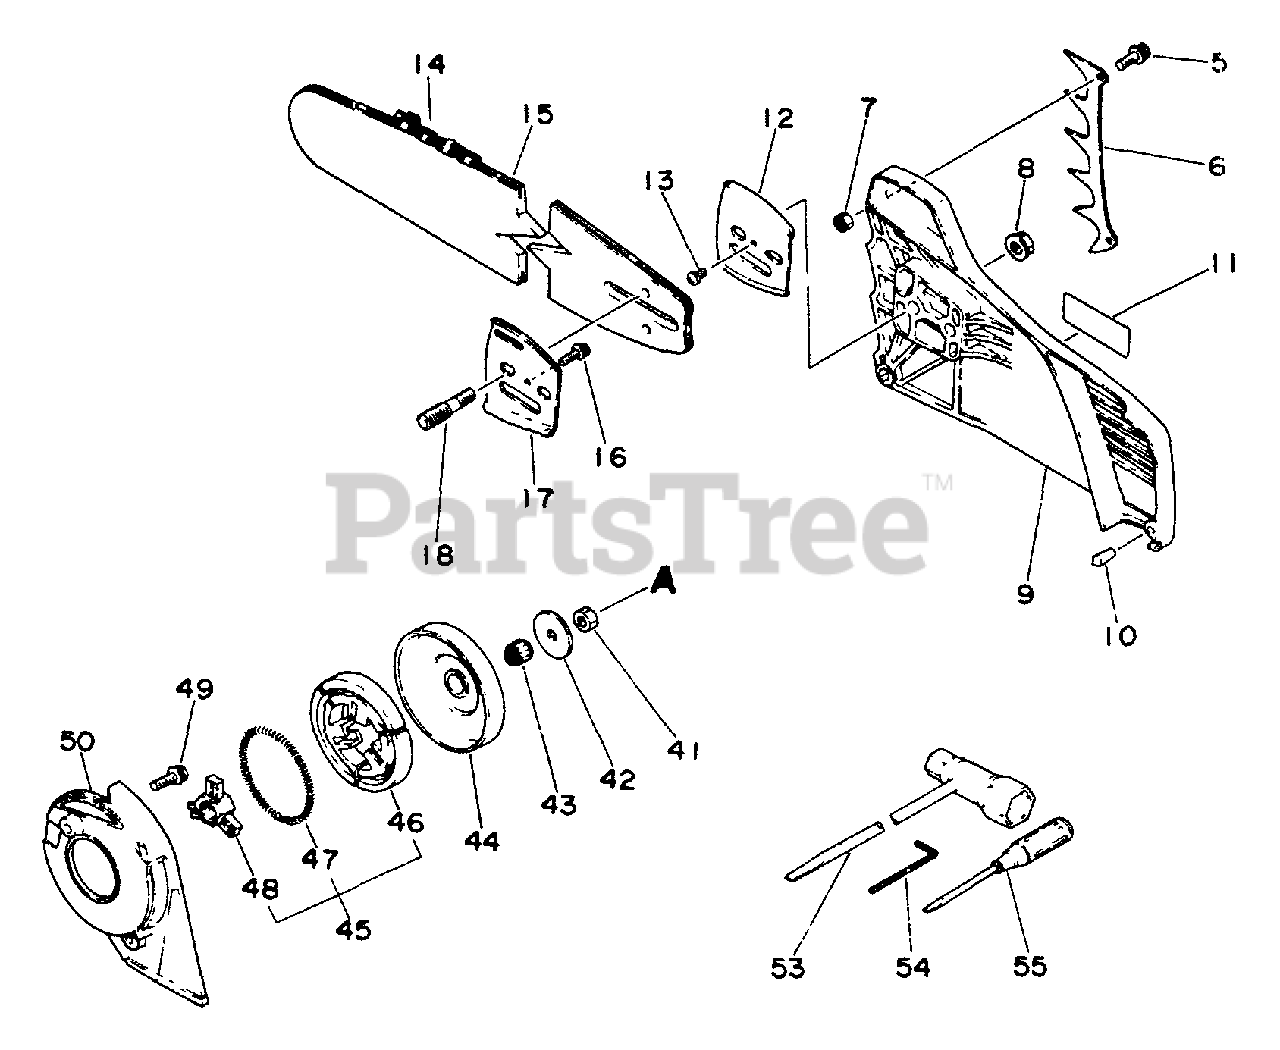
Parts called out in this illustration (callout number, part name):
5	SCREW - 5X12
6	SPIKE
7	LOCKNUT - 5
8	NUT - FLANGE
9	GUARD, SPROCKET
10	PIN - LOCATING
11	LABEL - ECHO
12	PLATE, GUIDE - OUTER
13	SCREW - 3X6
14	Chain
15	GUIDE BAR
16	SCREW - 4X12
17	PLATE, GUIDE - INNER
18	STUD, GUIDE BAR
41	LOCKNUT
42	WASHER, CLUTCH
43	BEARING, NEEDLE
44	DRUM, CLUTCH
45	CLUTCH ASSY
46	SHOE, CLUTCH
47	SPRING, CLUTCH
48	HUB, CLUTCH
49	SCREW - 5X16
50	SEAL, DUST
53	T-WRENCH - 13X19mm
54	HEX KEY - 4mm
55	SCREWDRIVER
